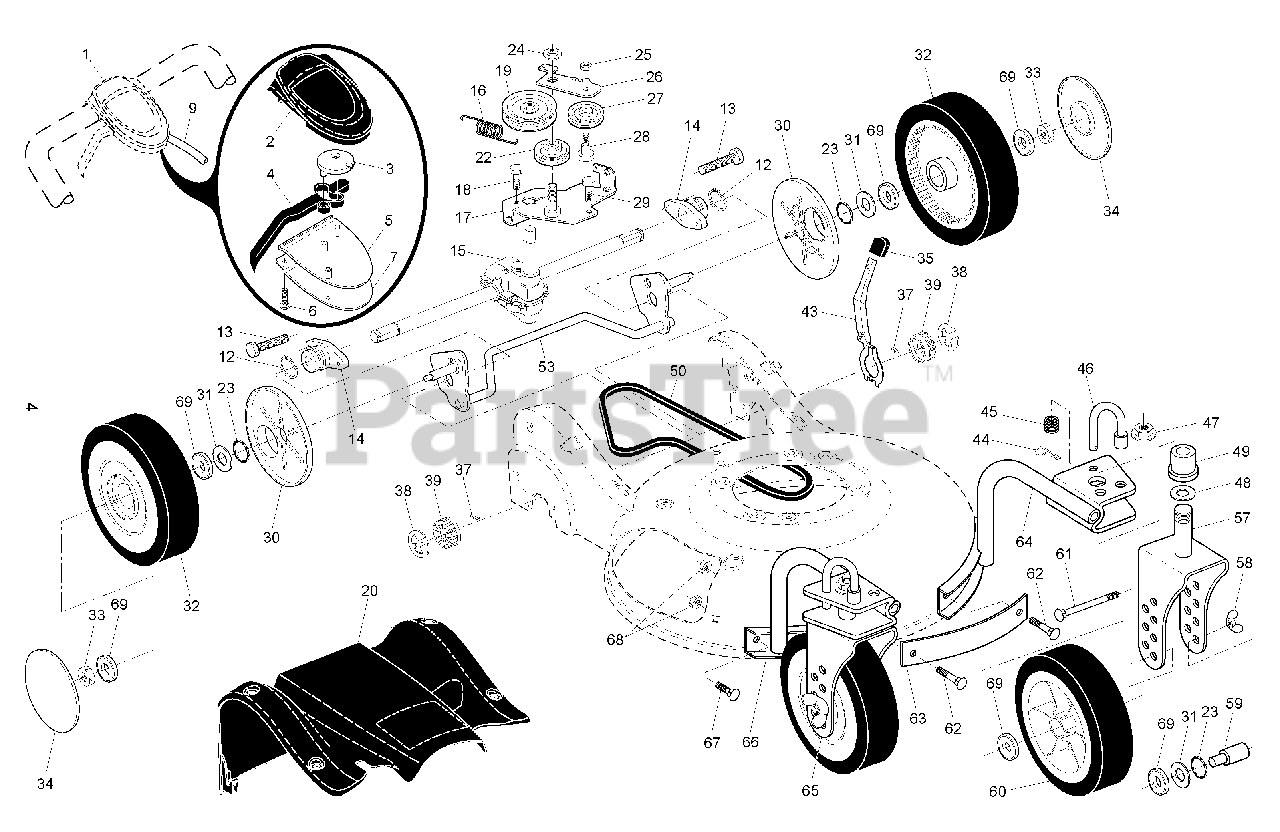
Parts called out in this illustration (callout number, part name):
1	Drive Control Assembly, Complete
2	Cover, Drive Control, Top
3	Pulley, Drive Control
4	Lever, Drive Control
5	Cover, Drive Control, Bottom
6	Screw, Torx Head #8-5/8
7	Bracket, Mounting, Drive Control
9	Cable, Drive Control
12	Ring, Retaining
14	Bearing / Axle Support
15	Gear Case Assembly, Complete
16	Spring, Return
17	Belt Keeper
19	Pulley, Drive
20	Drive Cover Assembly
22	Pulley Assembly, V-Groove
23	O-Ring
24	Nut, Hex, Flangelock
25	Nut, Hex, Lock
27	Pulley, Idler
28	Bolt, Hex Head, Shoulder
29	Screw 1/4-20 x 1/16
30	Cover, Dust, Wheel
31	Washer, Flat 3/8
32	Wheel Assembly, Rear 9 x 2-1/4
33	Nut, Hex
35	Knob, Star
43	Lever, Selector, Wheel Height, Rear
44	Clip, Retainer
47	Nut, Hex, Flangelock
48	Washer, Flat 1/2
50	Belt, Drive
53	Rear Axle Assembly
55	Decal, Drive Control
57	Bracket, Caster Wheel, LH
58	Wing Nut 5/16-18
60	Wheel Assembly, Front 9 x 2-1/4
61	Bolt, Carriage 5/16-18 x 3-1/2
62	Bolt, Carriage 5/16-18 x 7/8
63	Strap, Front
64	Support Tube Assembly, LH
65	Bracket, Caster Wheel, RH
66	Support Tube Assembly, RH
67	Bolt, Carriage 5/16-18 x 5/8
68	Nut, Hex 5/16
69	Bearing, Ball (Wheel)
